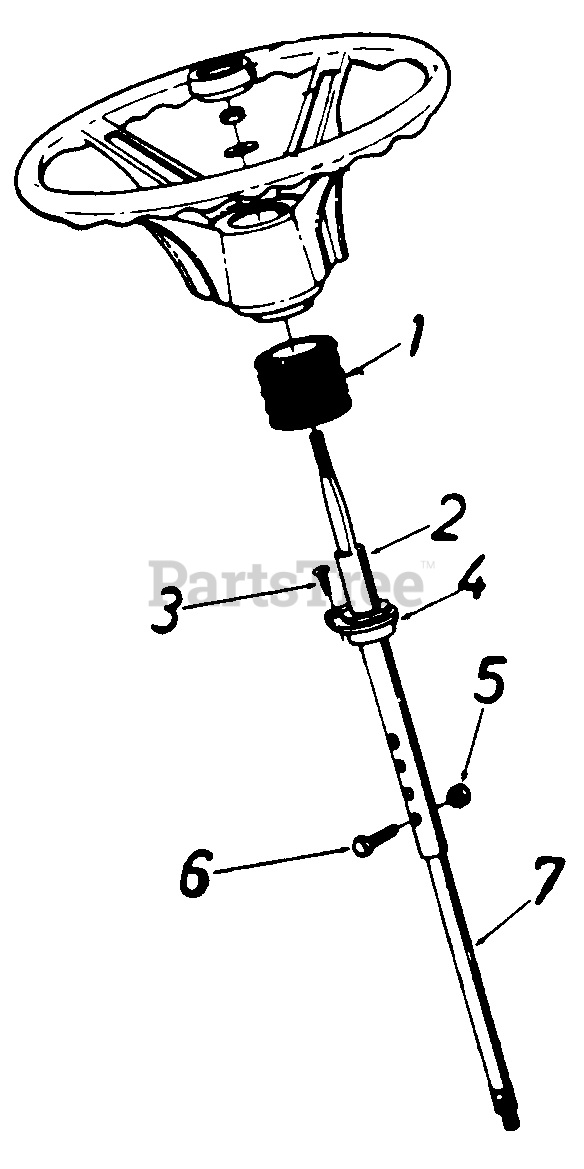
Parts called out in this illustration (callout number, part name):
1	Steering Bellow
2	Upper Steering Shaft
3	Oval Hd. C Sunk Scr. #10 x 5/8" Lg.
4	Fl Bearing .89" I.D. x 1.36" O.D.
5	Hex L Nut 1/4 20 Thd'
6	Hex Bolt 1/4-20 x 1.31" Lg.
7	Lower Steering Shaft
